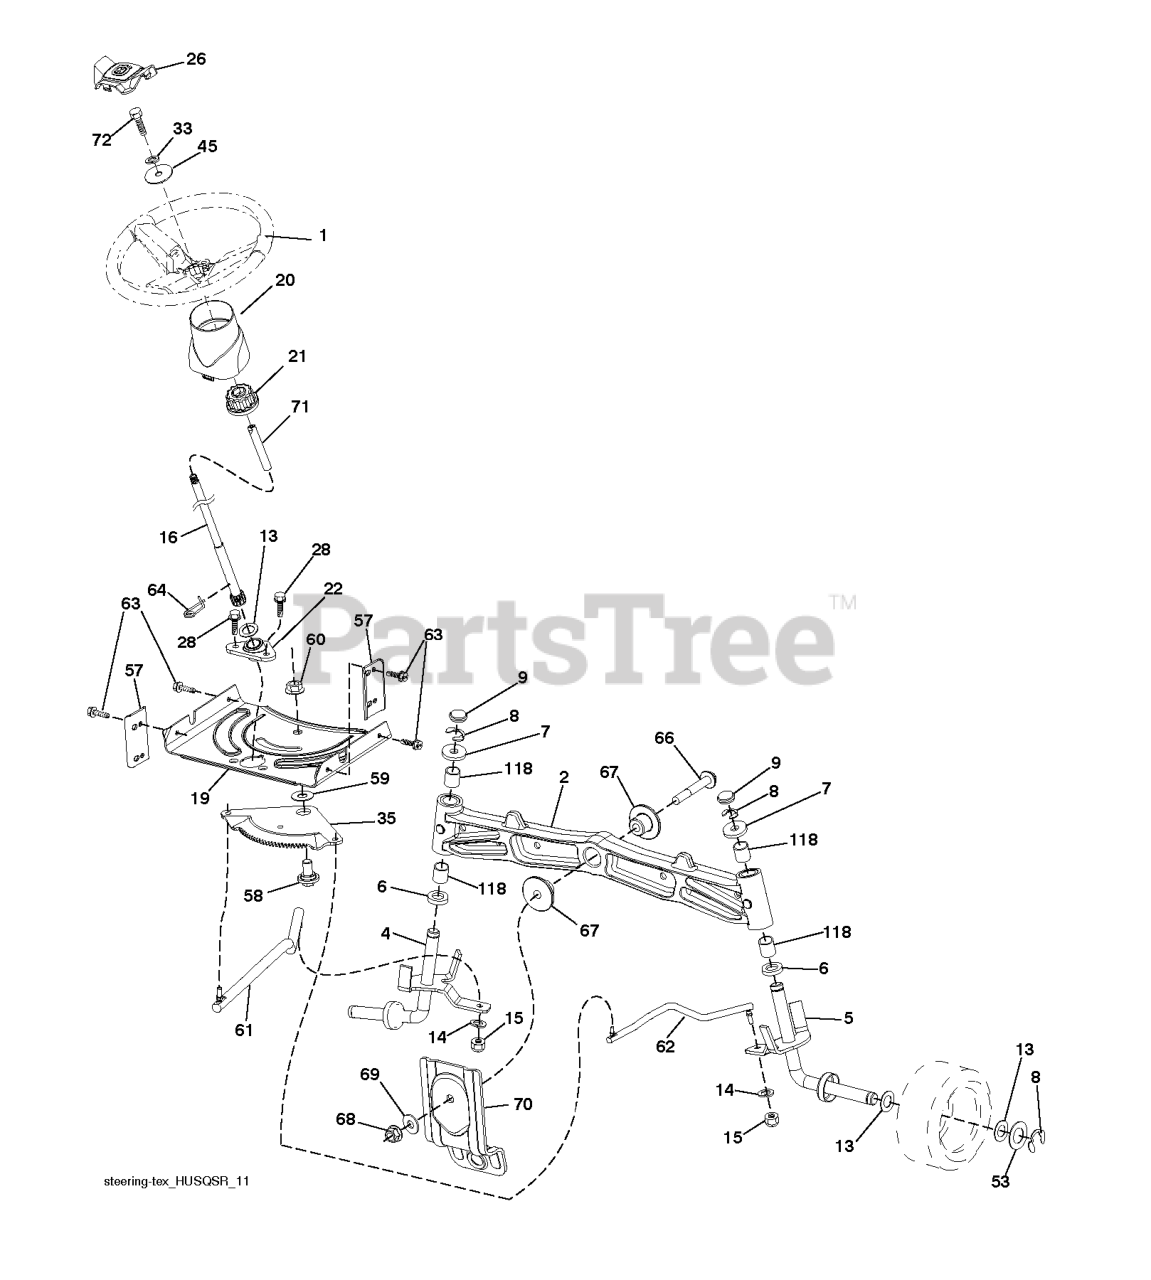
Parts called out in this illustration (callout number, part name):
1	DECAL READ OWNER'S MAN SYMS
3	DECAL.HOOD.HUSQVARNA.INTERNATI
5	DECAL.STEERING.HUSQ.BLUE
8	DECAL
10	DECAL BTRY SYMBOLS
11	DECAL.INTERNATIONL.CUTFINGER
12	DECAL
17	DECAL PARK BRAKE
20	DECAL.BYPASS.FENDER.CRD.LT.YT
